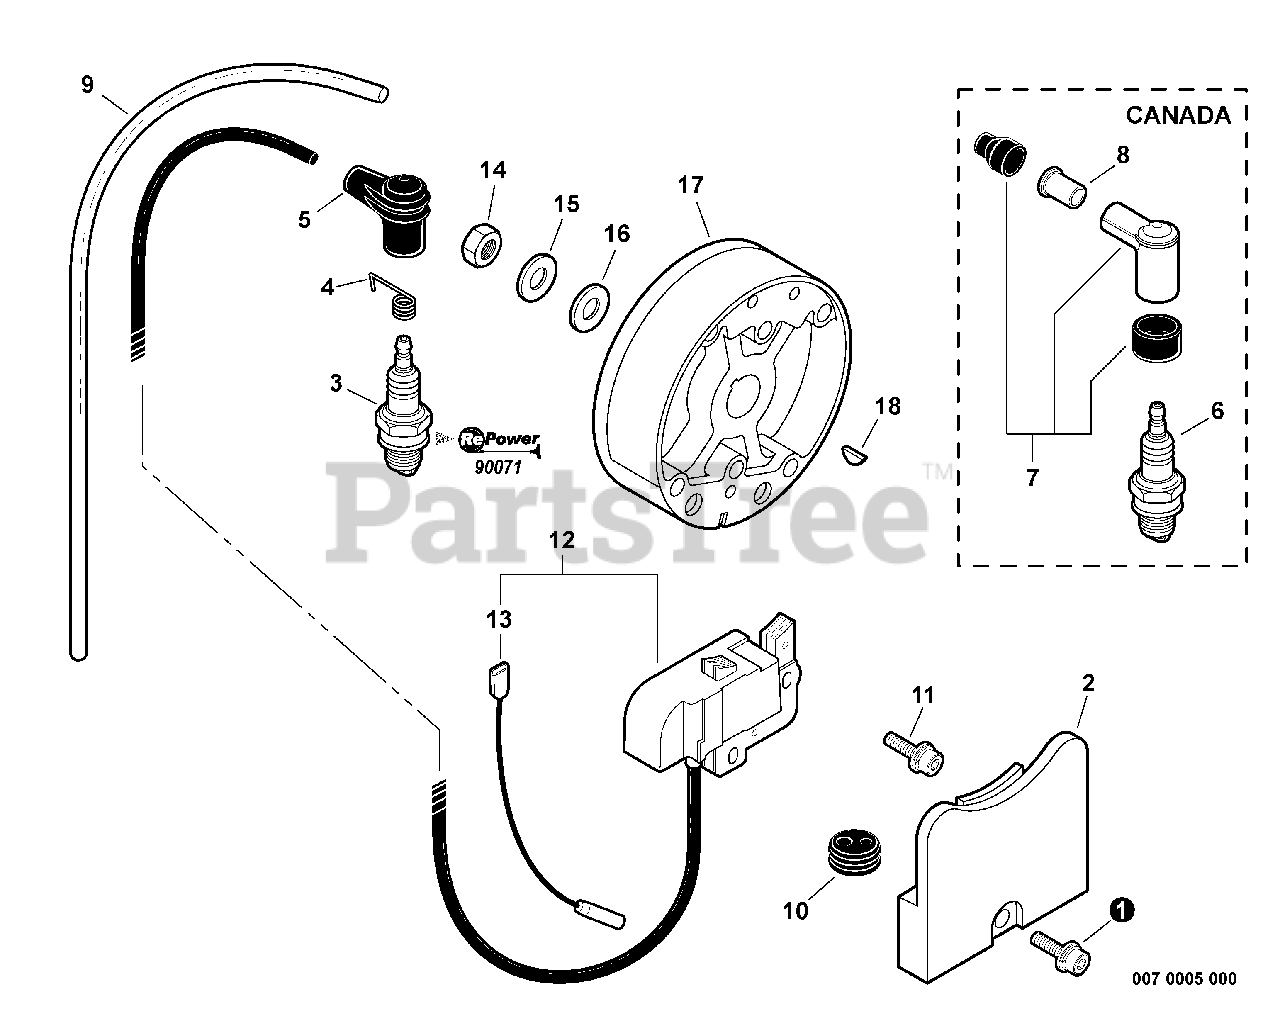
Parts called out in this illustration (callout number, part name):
1	BOLT 5×22
2	COVER, DUST
3	SPARK PLUG - BPM8Y
4	TERMINAL, SPARK PLUG
5	CAP, SPARK PLUG
6	SPARK PLUG - BPMR8Y
7	CAP, SPARK PLUG
8	ADAPTOR, SPARK PLUG - CAP
9	TUBE, VINYL 6.3×8×380
11	BOLT 5×22
12	COIL ASSY, IGNITION
13	LEAD - IGNITION
15	WASHER, SPRING 10
16	WASHER, SPRING 10
17	FLYWHEEL
18	KEY, WOODRUFF 3×14
19	TUNE-UP KIT - REPOWER
